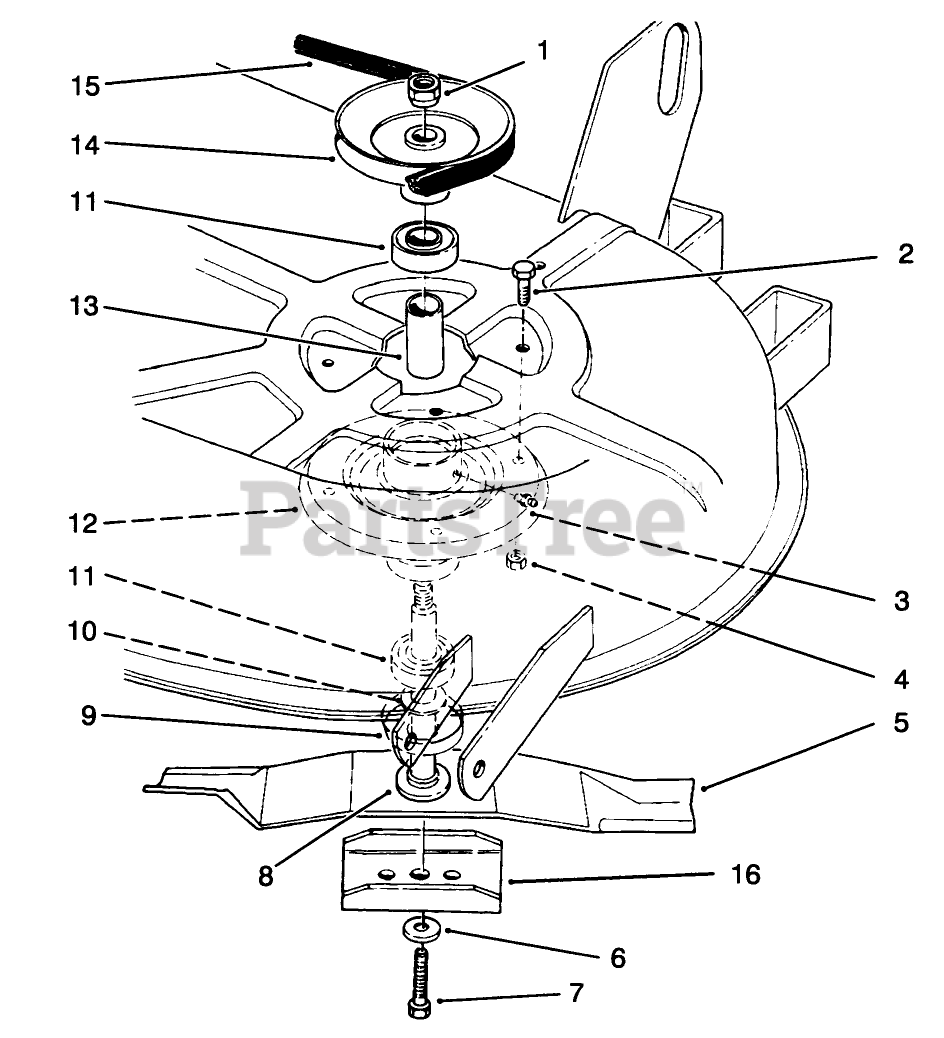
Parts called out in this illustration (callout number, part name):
1	Nut
2	SCREW-HH
3	ZERK FITTING
4	NUT-LOCK, NI
5	BLADE KIT
6	WASHER-BELLEVILLE
7	SCREW-HH
8	SHAFT-SPINDLE
9	SHIELD-BEARING
10	SPACER-HARDNED
11	BEARING-BALL
12	Housing-Spindle
13	SPACER
14	Pulley-Spindle
15	V-BELT
16	Stiffener
